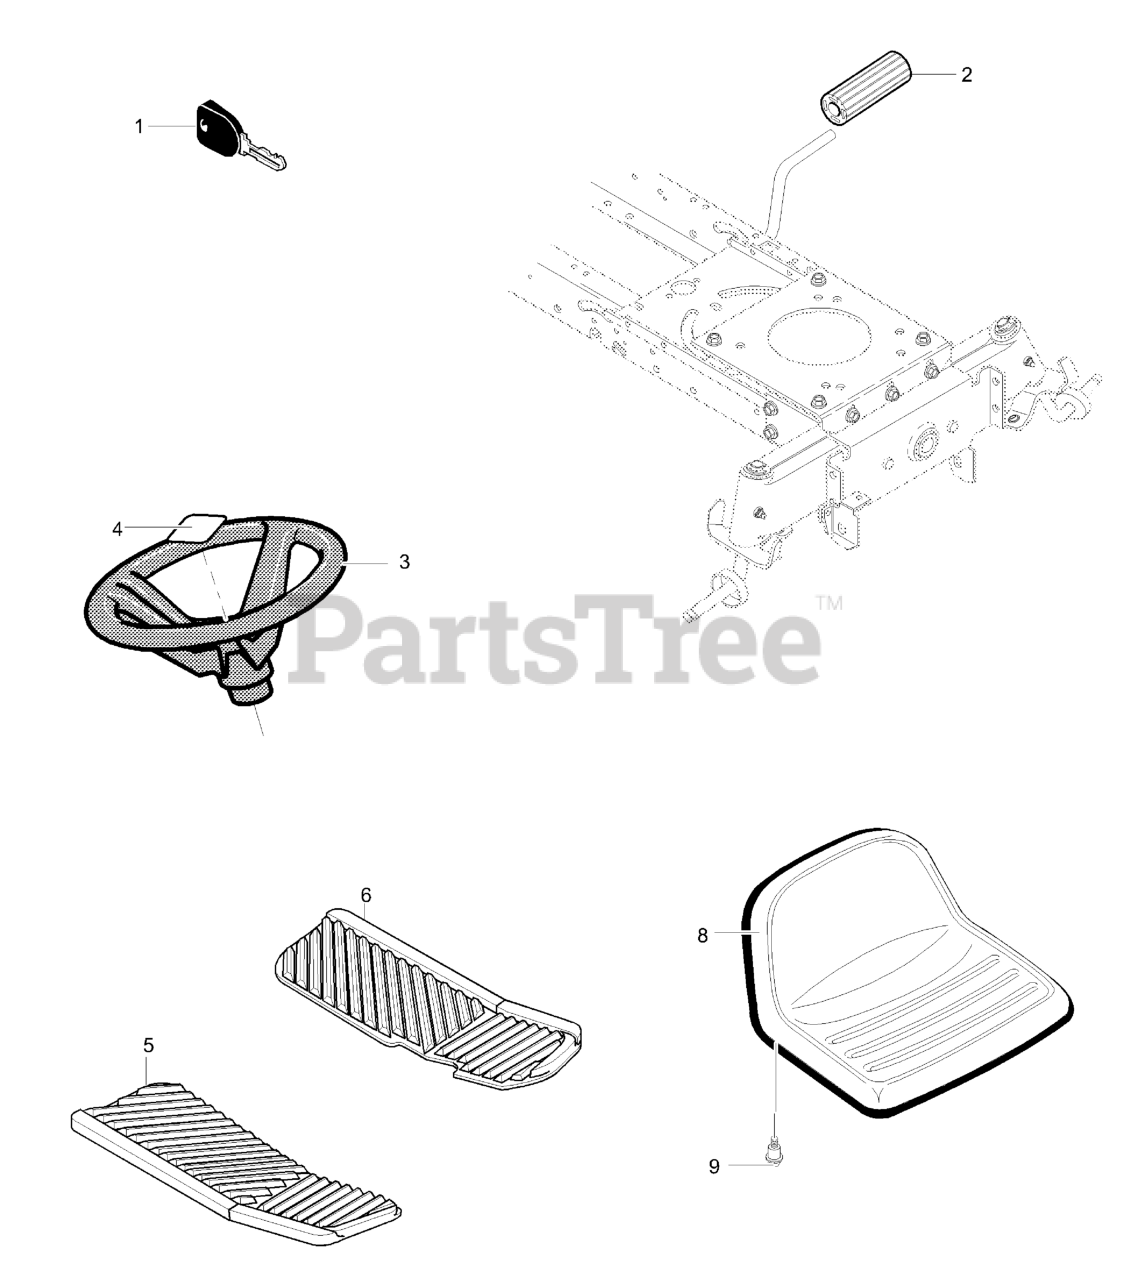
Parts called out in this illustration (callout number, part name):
1	Ignition Key
2	Cover, Pedal Brake/Clutch
3	Steering Wheel
4	Insert, 4-Spoke
5	Foot Pad RH
6	Foot Pad LH
9	Shoulder Bolt 5/16-18
